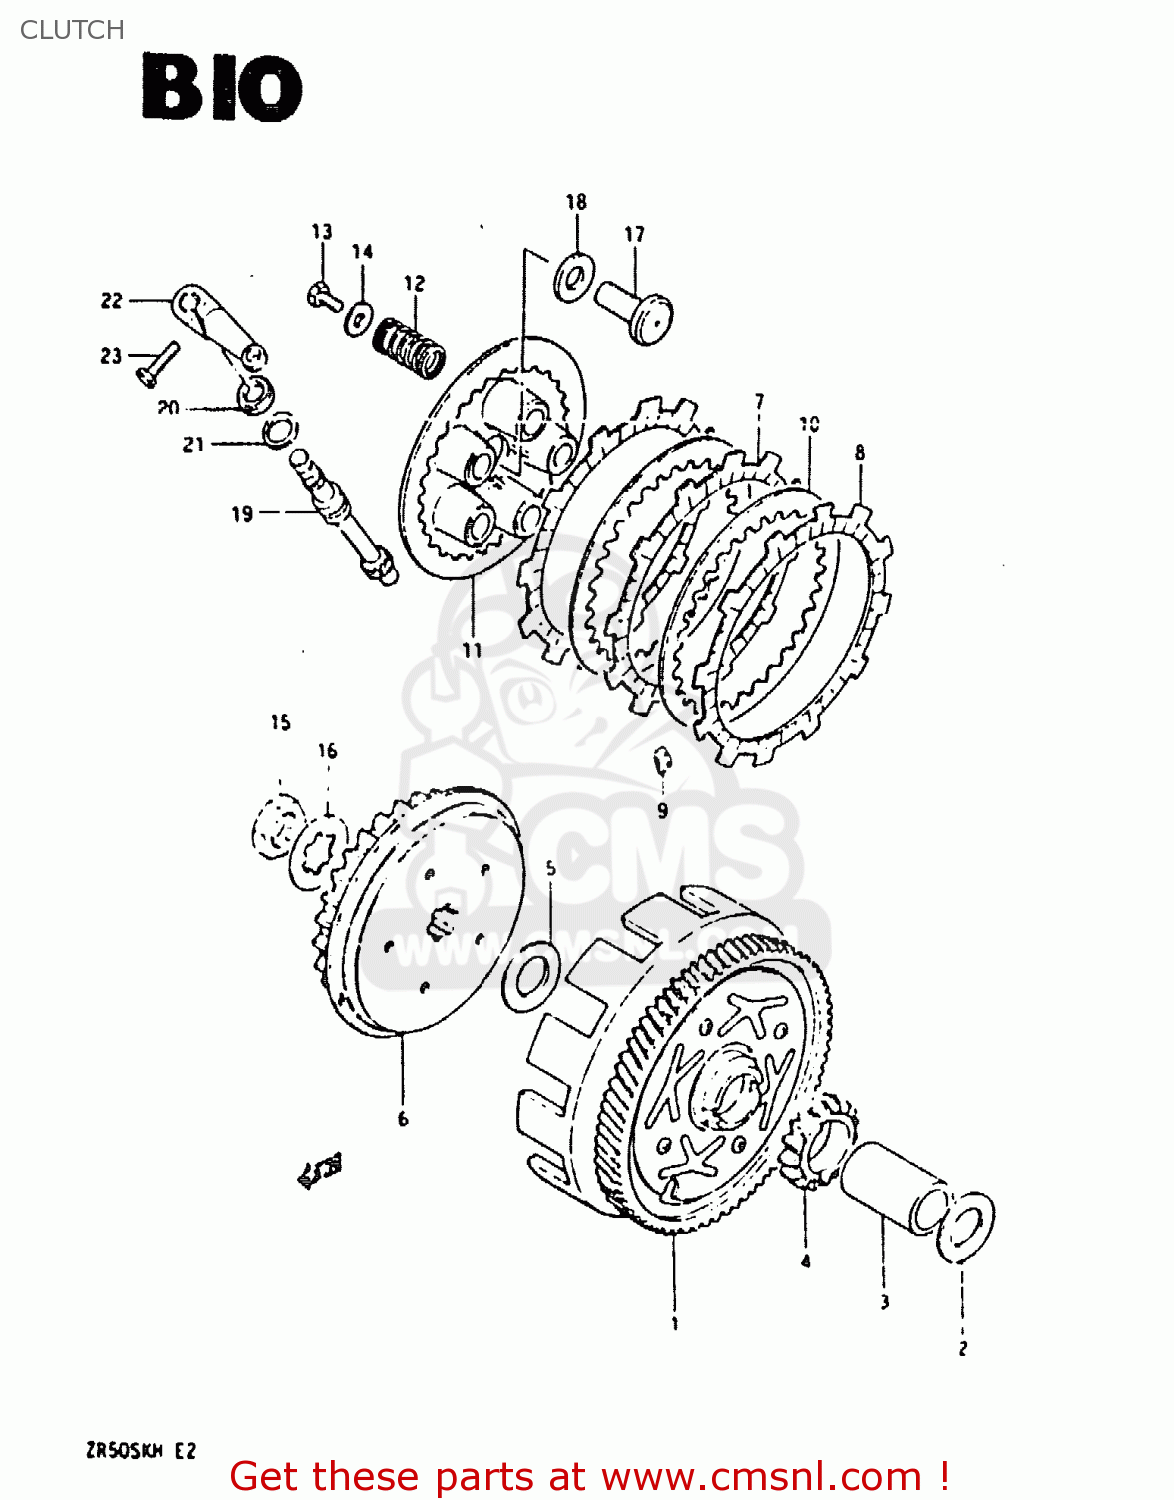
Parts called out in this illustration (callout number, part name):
1	GEAR ASSY,PRI DRIVEN(NT:73)
2	WASHER,THRUST
3	SPACER
4	GEAR,KICK STARTER DRIVE
5	WASHER
6	HUB,CLUTCH SLEEVE
7	PLATE,CLUTCH DRIVE (NAS)
8	PLATE,CLUTCH DRIVE (NAS)
9	DAMPER
10	PLATE,CLUTCH DRIVEN (NAS)
11	DISC,CLUTCH PRESSURE
12	SPRING
13	BOLT(5X16)
14	WASHER (5.5X16X1.2)
15	NUT
16	WASHER,LOCK
17	RACK,CLUTCH RELEASE
18	BEARING(10X22X2.8)
19	PINION,CLUTCH RELEASE
20	OIL SEAL
21	WASHER (12X17X1)
22	ARM,CLUTCH RELEASE
23	BOLT
